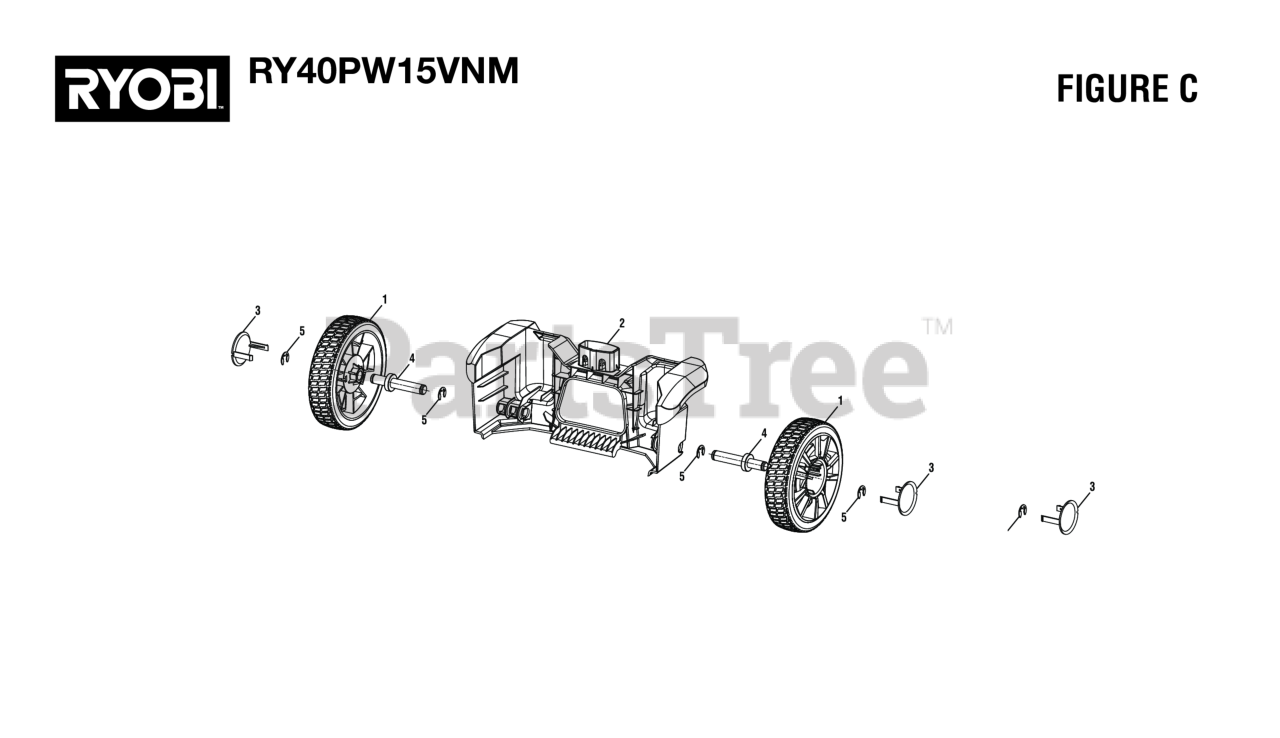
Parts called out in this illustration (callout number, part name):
2	Wheel Base Bracket
3	Wheel Cover
4	Wheel Axle
5	Retaining Ring
